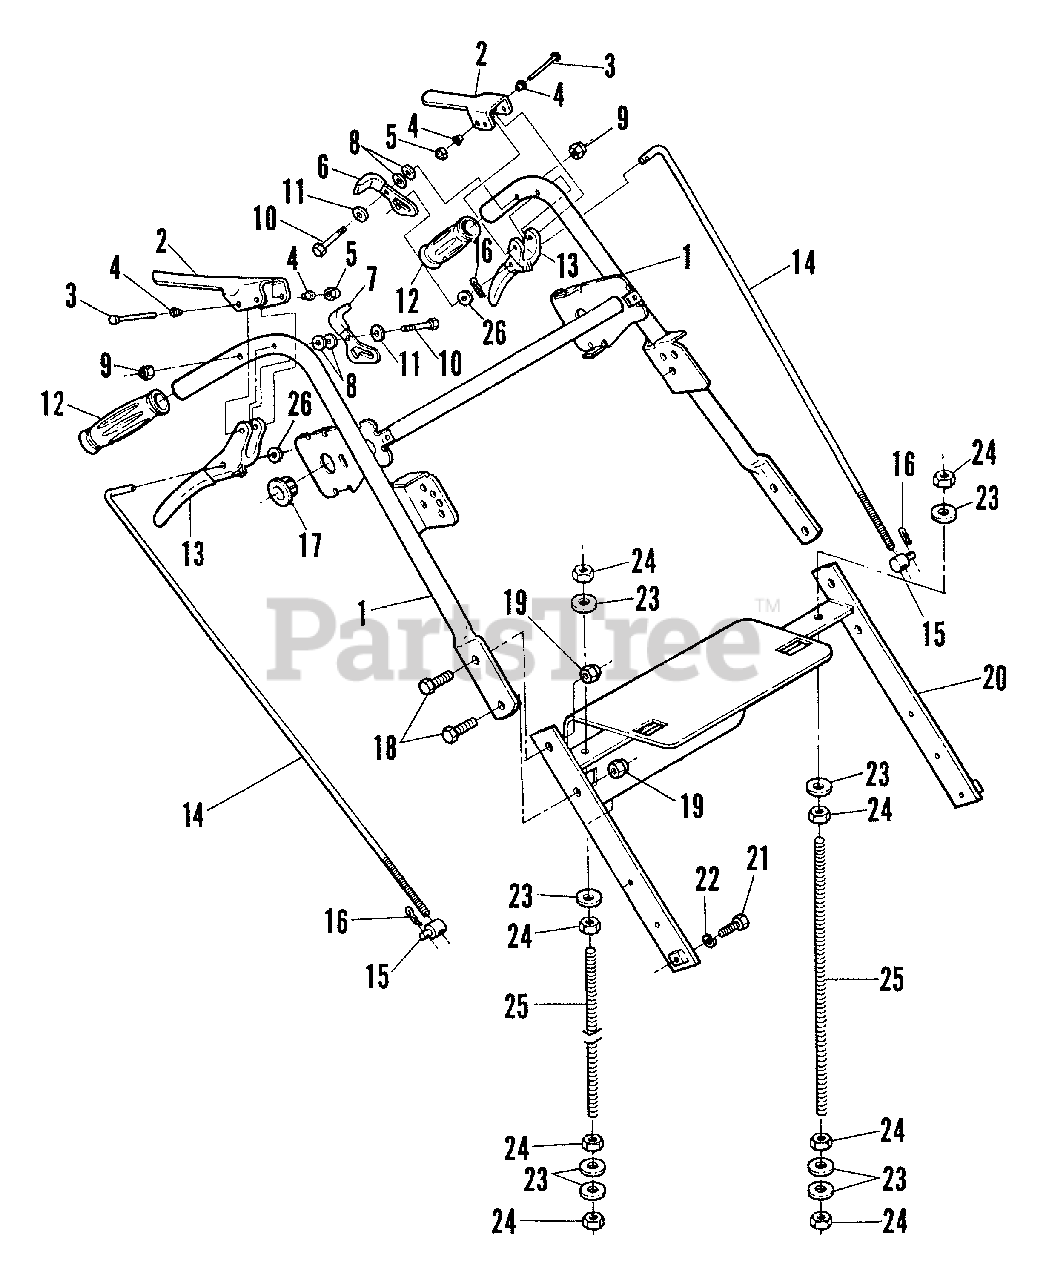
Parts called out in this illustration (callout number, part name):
1	HANDLE, Upper J-Weldment w/Decals
2	LEVER, Operator Presence w/Grip
3	PIN, 3/16 x 2-1/4" Clevis
4	BUSHING
5	NUT, 3/16" Push
6	LATCH, Thumb w/Grip
7	LATCH, Thumb w/Grip
8	WASHER, 1/4" SAE Flat
9	NUT, 1/4-20 Prevailing Torque
10	SCREW, 1/4-20 x 1-1/2" Hex Head Cap, Grade 5
11	WASHER, 1/4" Spring Wave
12	GRIP, Handle
13	LEVER, Traction w/Grip
14	ROD, Traction
15	SWIVEL, Long
16	HAIRPIN, #2 Cotter
17	BUSHING, Snap
18	SCREW, 3/8-16 x 1" Hex Head Cap, Grade 5
19	NUT, 3/8-16 Hex Nyloc
20	HANDLE, Lower
21	SCREW, 3/8-16 x 1-1/4" Hex Head Cap, Grade 5 92)
22	WASHER, 3/8" Split Lock
23	WASHER, 1/2" Split Lock
24	NUT, 1/2-13 Regular Hex
25	BRACE, Handle
26	WASHER, 5/16" Standard Flat
